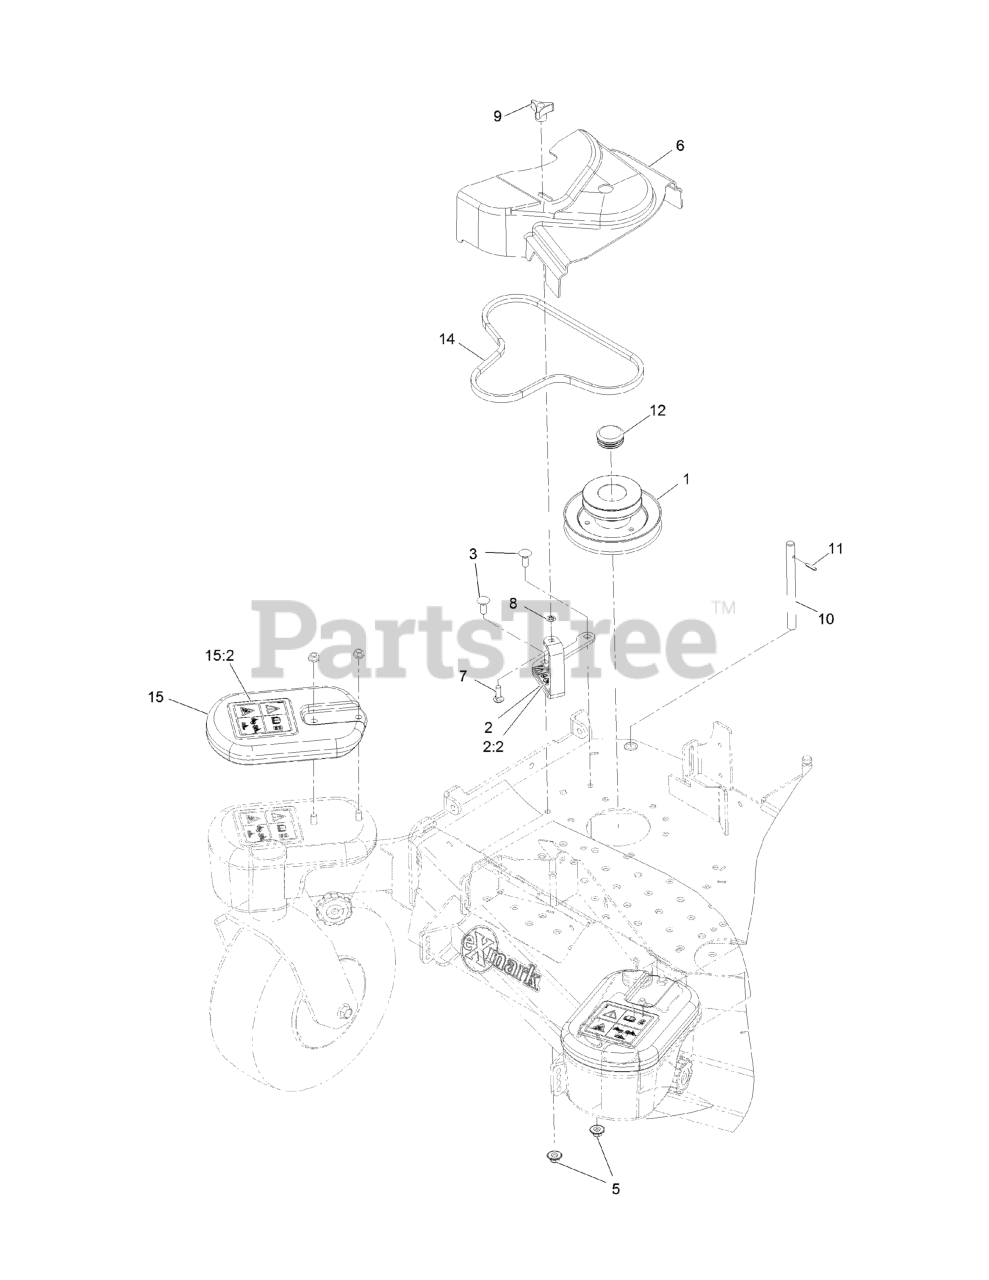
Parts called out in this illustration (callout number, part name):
1	JACKSHAFT- UV DRIVE 483
2	ASM-CVR BRKT W/DECAL
2:2	DECAL-DANGER
3	BOLT-CARR
5	Nut-Nyloc 3/8-16 Flg
6	COVER-BELT, UV 48
7	BOLT-CARR
8	RING-RETAINING, BOLT
9	KNOB-3 PRONG
10	SHAFT-CATCHER, GRASS
11	PIN-ROLL
12	PLUG-ROUND PLASTIC
14	BELT-BLOWER
15:2	DECAL-WARNING, TRACTION
